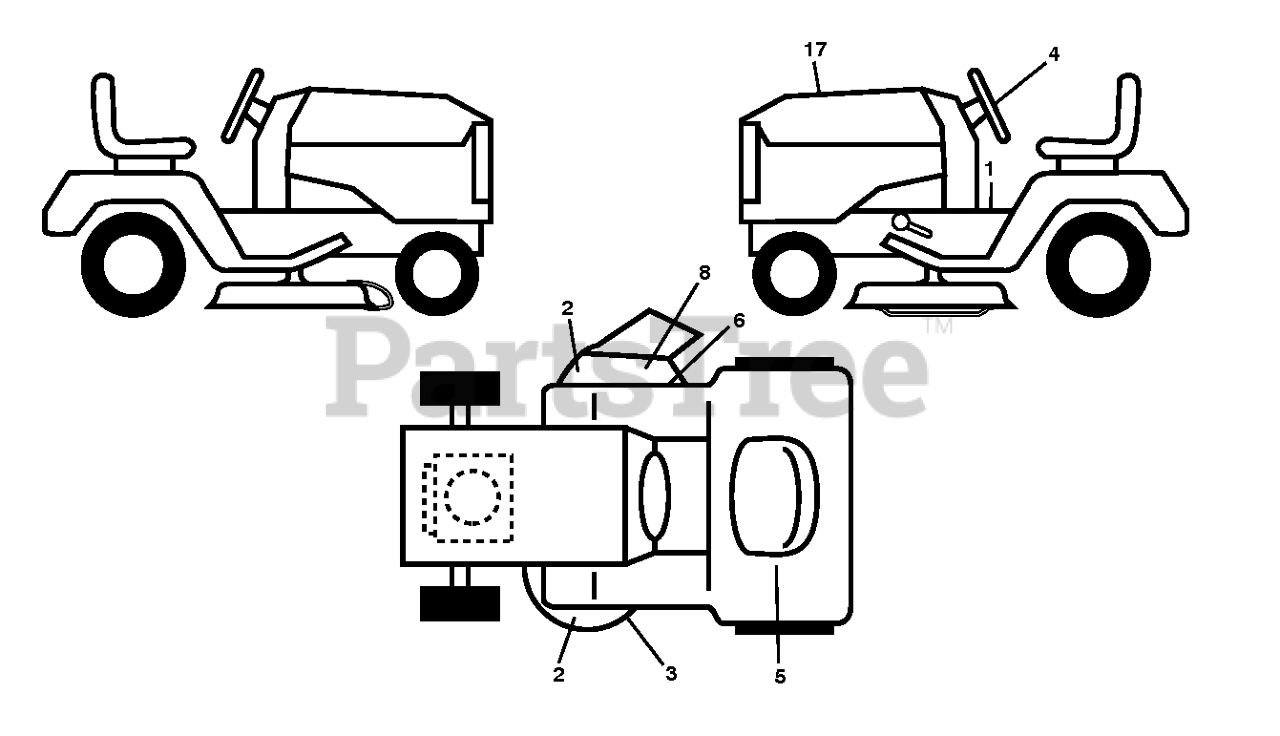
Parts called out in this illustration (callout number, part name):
1	DECAL.FENDER.WARNING.ENGLISH
2	DECAL.DECK.CLEARCUT.NOSTEP
3	DECAL CLIP.TRIM.W DECAL.DECK.L
4	DECAL STEERING WHEEL DECAL DEC
5	DECAL.WARN.FUEL.RESERVE
6	DECAL BELT ROUTING DECAL DECAL
8	DECAL DECK WARNING GRAPHIC DEC
17	DECAL.RPL.KW.FR7.TLB.54F
